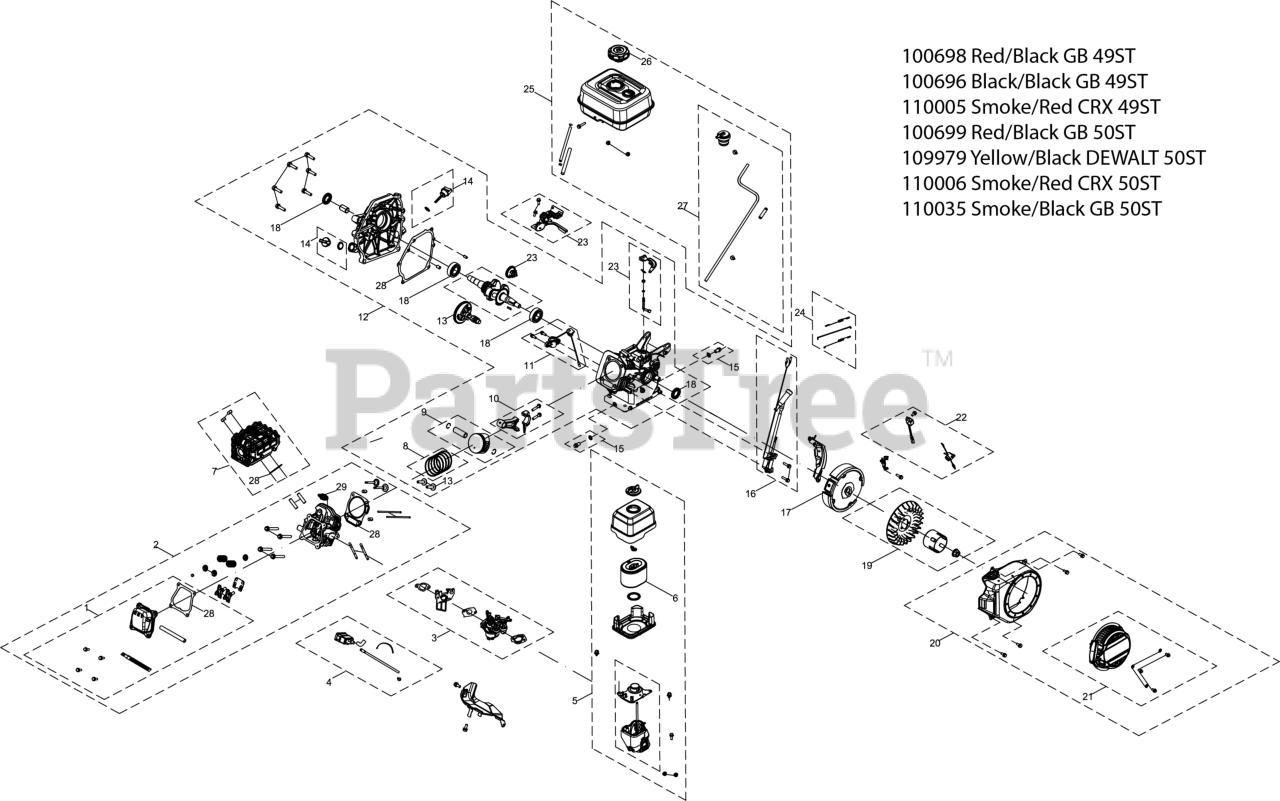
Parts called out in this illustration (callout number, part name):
1	VALVE COVER KIT
2	CYLINDER HEAD KIT
3	CARBURETOR KIT
4	CARBON CANISTER KIT
5	AIR FILTER ASSEMBLY
6	AIR FILTER ELEMENT
7	MUFFLER KIT
8	PISTON RING SET
9	PISTON KIT
10	CONNECTING ROD KIT
11	LOW OIL SENSOR KIT
12	SHORT BLOCK KIT
13	CAM&TAPPET SET
14	OIL DIP STICK KIT
15	OIL DRAIN PLUG KIT
16	IGNITION MODULE KIT
17	FLY WHEEL
18	OIL SEAL AND BEARING KIT
19	STARTER CUP/FAN KIT
20	RECOIL & BLOWER HOUSING KIT
21	RECOIL STARTER KIT
22	ON/OFF SWITCH KIT
23	ADJUSTABLE THROTTLE & GOVERNOR KIT
24	GOVERNOR SPRING KIT
25	FUEL TANK KIT
26	FUEL CAP
27	ROLL OVER VALVE KIT
28	ENGINE GASKET KIT
29	SPARK PLUG
